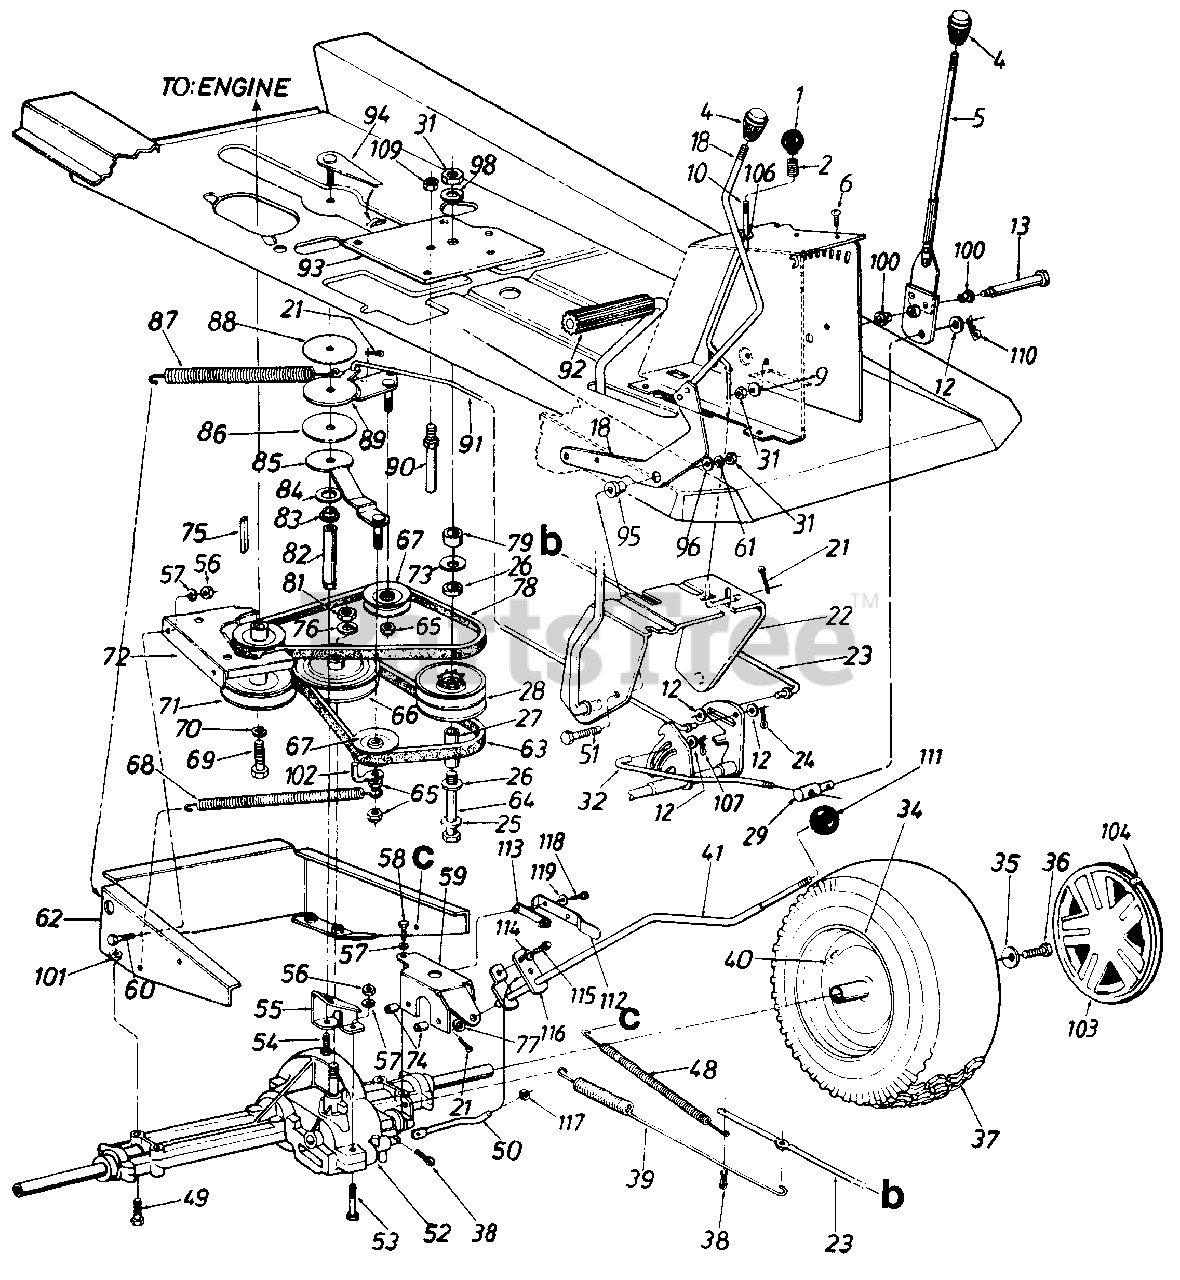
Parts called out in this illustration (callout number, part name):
1	Ball Knob 1/4-20 Thd.
2	Compression Spring
4	Shift Knob
5	Shifter Ass'y. w/Handle
6	Pan Hd. Tap Scr. #12 x .5" Lg.
9	Bell-Wash. .4" I.D.
10	Parking Brake Rod
12	Fl-Wash. .34" I.D. x .68" O.D.
13	Shld. Bolt .498" Dia. x 4.75" Lg
24	Cotter Pin 1/8" Dia. x 1.0"
25	Fl-Wash. .406" I.D. x 1.125"
26	Thrust Brg. .56" I.D.
27	Spacer Sleeve 2.71" Lg.
28	Variable Speed Pulley Ass'y.
29	Ferrule
31	Hex Nut 3/8-16 Thd.
32	Speed Control Link
35	Bell-Wash. .345" I.D. x .88"
36	Hex L-Bolt 5/16-24 x .75" Lg.
38	Cotter Pin 1/8" Dia. x 1.25"
39	Extension Spring 17" Lg.
40	Air Valve
41	Shift Lever Ass'y.
48	Extension Spring 8.25" Lg.
49	Hex Bolt 5/16-18 x 2.5" Lg.
50	Shift Rod
51	Hex Bolt 3/8-16 x 1.25" Lg.
52	Transaxle
53	Hex Bolt 1/4-20 x 1.75" Lg.
54	Hex Bolt 3/8-24 x .75" Lg.
57	L-Wash. 1/4" I.D.
58	Self-Tap Mach. Scr. 1/4-20 x 1.37" Lg.
59	Shift Lever Support Brkt.
60	Hex Bolt 1/4-20 x 1.0" Lg.
61	L-Wash. 3/8" I.D.
64	Hex Bolt 3/8-16 x 4.5" Lg.
65	Hex L-Nut 3/8-24 Thd.
66	"V"-Pulley
67	"V"-Belt Idler
68	Ext. Spring 6.37" Lg.
69	Hex Bolt 7/16-20 x 1.0" Lg.
70	L-Wash. 7/16" I.D.
71	Engine Pulley
72	Upper Belt Guard
73	Bell-Wash. .40" I.D. x 1.12" O.D.
74	Spacer .256" I.D. x .5" O.D.
75	Sq. Key 1/4" x 2.0" Lg.
76	Bell-Wash. .567" I.D. x 1.125"
77	Fl-Wash. .469" I.D. x .88" O.D.
78	"V"-Belt
79	Spacer .38" I.D. x 1.0" O.D.
81	Hex Jam Nut 9/16-18 Thd.
82	Torque Rod
83	Flange Bearing .378" I.D.
84	Fl-Wash. .64" I.D. x 1.24" O.D.
85	Idler Bracket Ass'y.
86	Thrust Washer .635" I.D.
87	Extension Spring 7.58" Lg.
88	Thrust Wash. .385" I.D.
89	Idler Bracket Ass'y. For Clutch
90	Belt Guard Pin 3/8-16 x 2.75" Lg.
91	Clutch Rod
92	Foot Pad
96	Fl-Wash. .406" I.D. x 1.25" O.D.
98	L-Wash. 3/8" I.D. (Heavy Duty)
100	Flanged Nyliner Brg.
101	Hex Sems Nut 5/16-18 Thd.
102	Belt Guard
104	Spring Clip
106	Fl-Wash. .281" I.D. x .5" O.D.
107	Intern. Cotter Pin 1-1/8" Lg.
109	Hex Top L-Jam Nut 3/8-16 Thd.
110	Internal Cotter Pin 3/8" Dia.
111	Ball Knob
112	Spring Switch
113	Insulator Nut Plate
114	Bell-Wash. .265" I.D. x .75" O.D.
115	Hex Bolt 1/4-20 x .5" Lg.
116	Shift Lever Adjusting Link
117	Retaining Ring
118	Hex Wash. Hd. Scr. #8 x .5" Lg.
119	Plastic Washer
